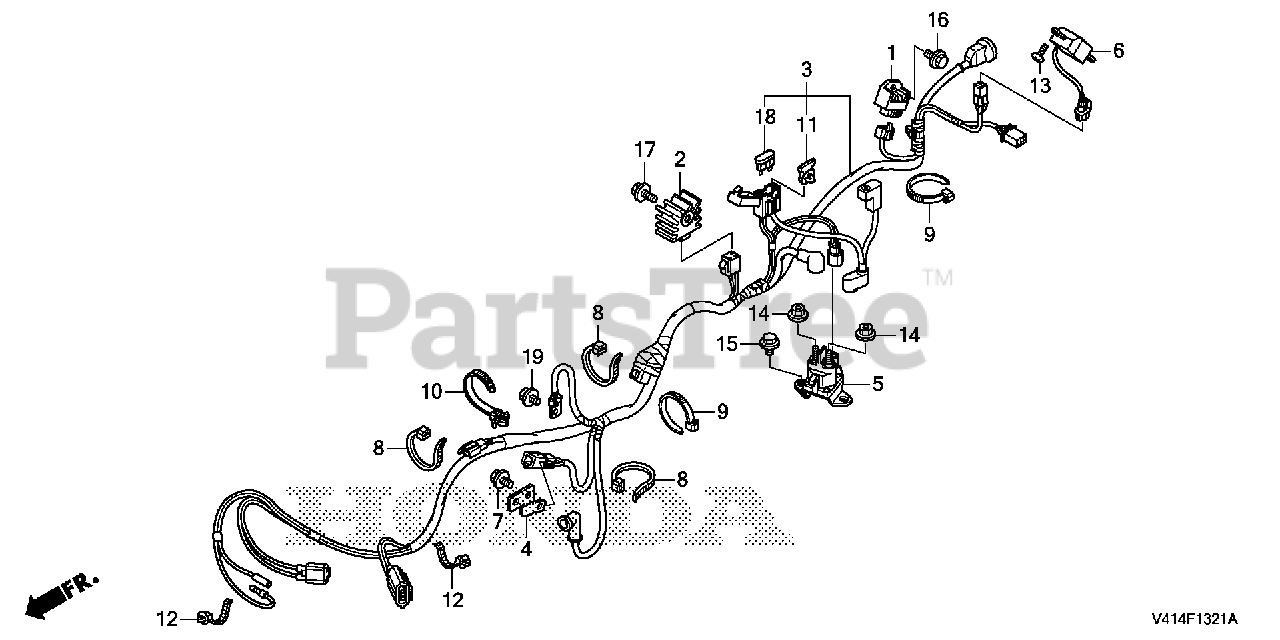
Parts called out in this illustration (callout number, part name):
2	RECTIFIER, REGULATOR (5A)
3	WIRE HARNESS ASSY., MAIN
4	BASE, CLIP
5	SWITCH ASSY., STARTER MAGNETIC
7	BOLT, FLANGE (6X12) (CT200)
8	BAND, WIRE (95MM)
9	BAND, WIRE (165MM) (BLACK)
10	STRAP, CABLE (118MM) *NH1L* (Honda Code 1170653). (BLACK)
11	CLIP, CONNECTOR (BEIGE)
12	CLIP, HARNESS BAND (145MM) (BLACK)
14	NUT, FLANGE (6MM)
15	BOLT, FLANGE (6X10)
16	BOLT, FLANGE (6X12) Use up to Engine SN 1543277.
17	BOLT, FLANGE (6X30)
18	FUSE, MINI (5A)
19	BOLT, FLANGE (6X12) (CT200)
19	BOLT, FLANGE (6X10)
